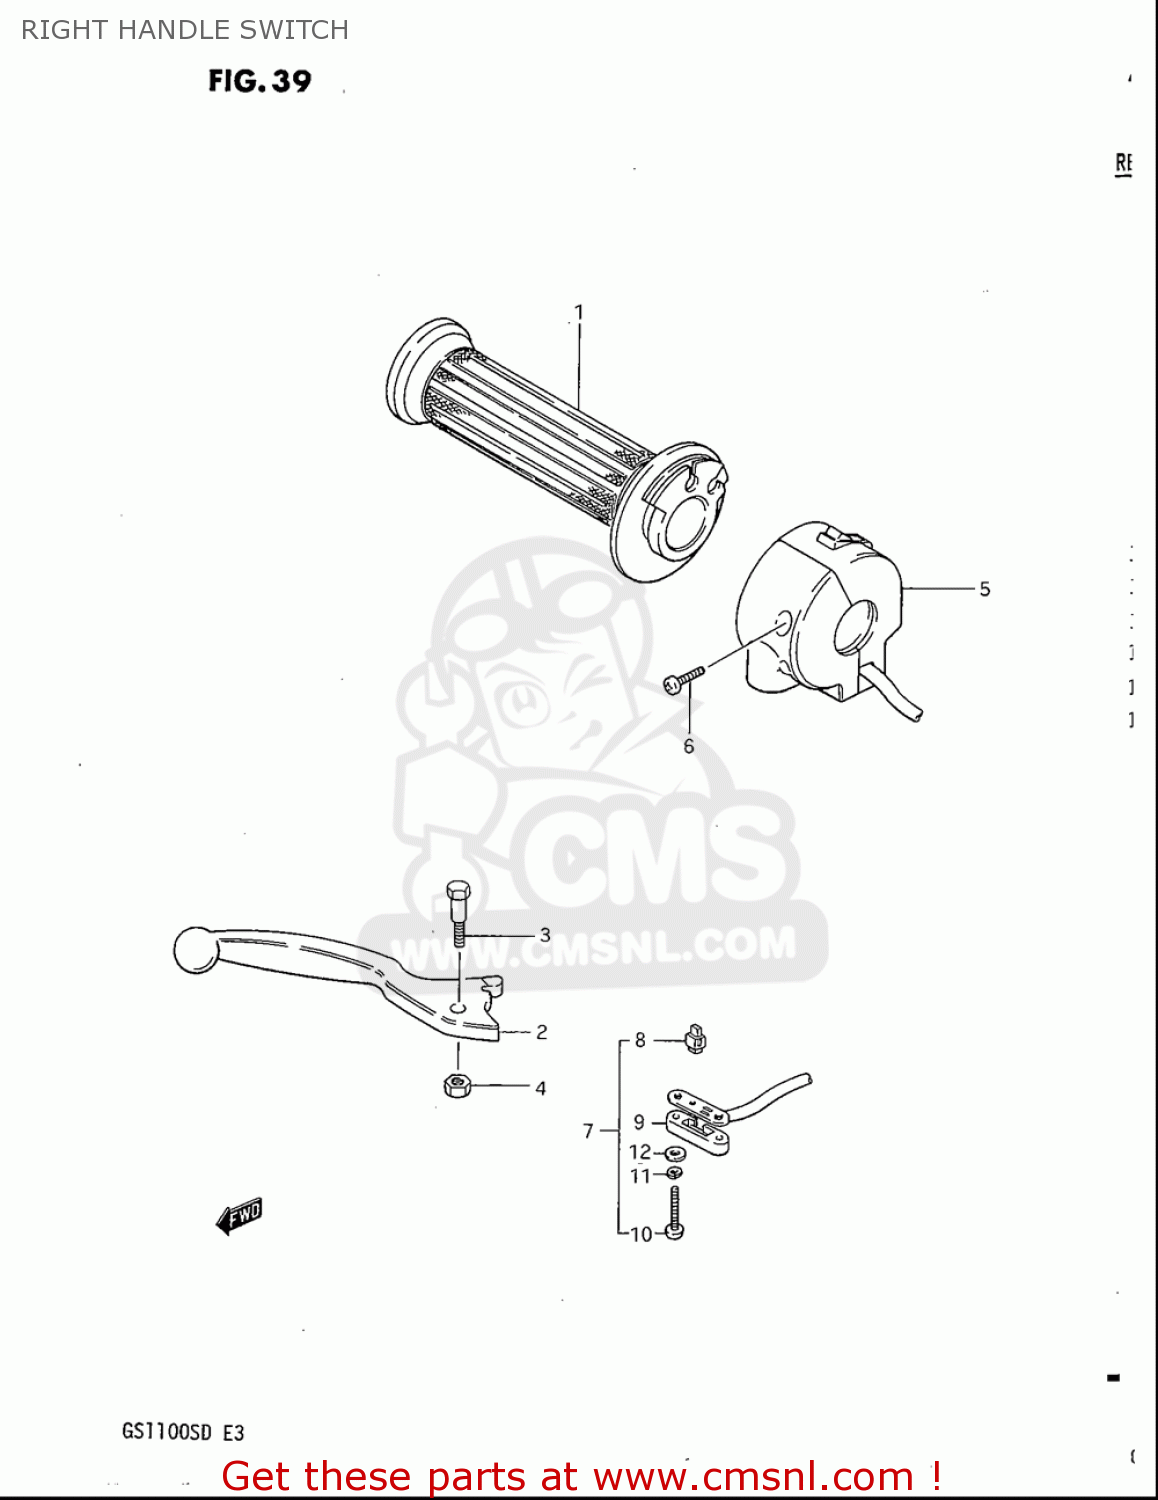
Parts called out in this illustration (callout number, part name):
1	GRIP,THROTTLE
2	LEVER,BRAKE
3	BOLT
4	NUT 6MM
5	SWITCH ASSY,HANDLE,R
6	SCREW(5X14)
7	SWITCH ASSY,STOP
8	CONTACT,SWITCH
9	COVER,FR BK TERMINAL BASE
10	SCREW
11	WASHER,LOCK
12	WASHER
